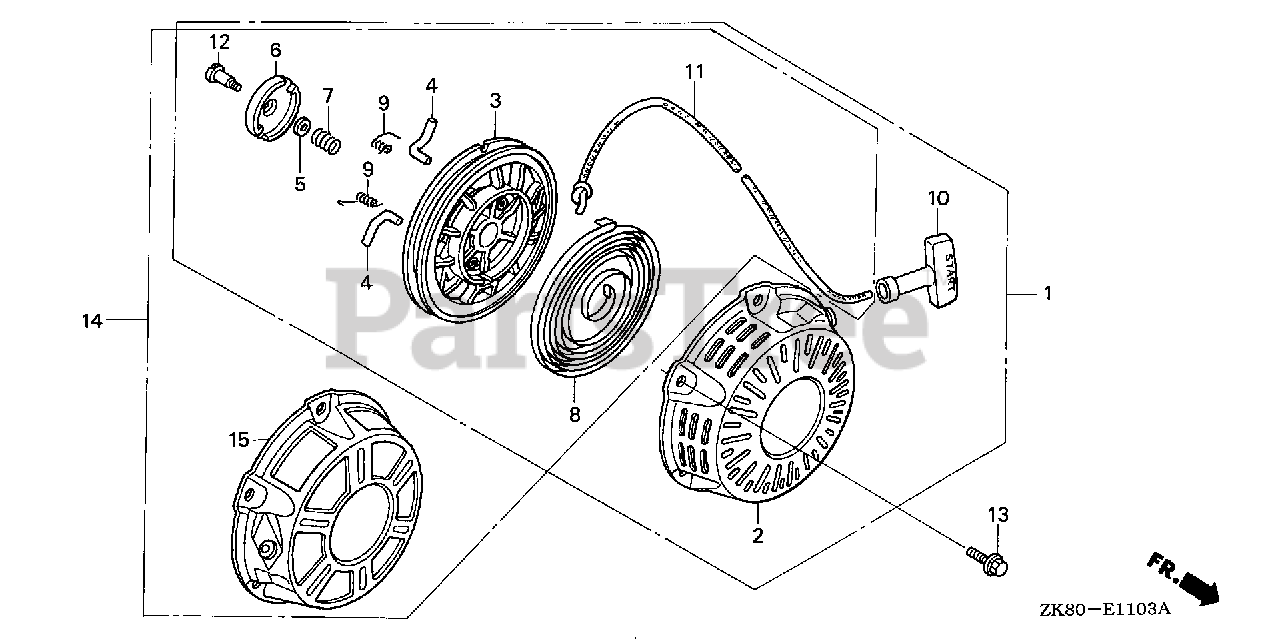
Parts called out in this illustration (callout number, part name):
1	STARTER ASSY., RECOIL *R280* (POWER RED)
1	STARTER ASSY., RECOIL *NH1* (BLACK)
2	CASE, RECOIL STARTER *R280* (POWER RED)
2	CASE, RECOIL STARTER *NH1* (BLACK)
3	REEL, RECOIL STARTER (BLACK)
4	RATCHET, STARTER
5	PLATE, FRICTION
6	GUIDE, RATCHET
7	SPRING, FRICTION
8	SPRING, RECOIL STARTER
9	SPRING, RETURN
10	GRIP, STARTER
10	KNOB, RECOIL STARTER
11	ROPE, RECOIL STARTER
12	SCREW, SETTING
13	BOLT, FLANGE (6X10)
